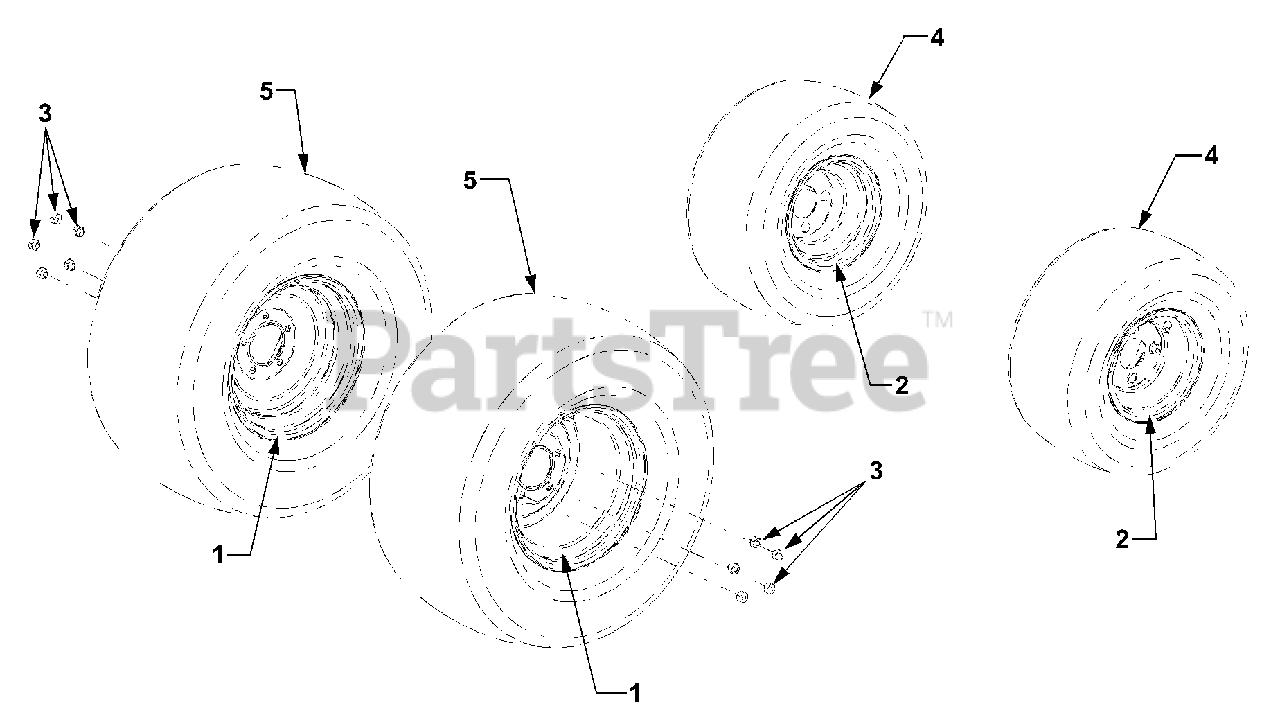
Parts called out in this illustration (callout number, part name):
1	Rim Assembly
2	Rim Assembly
3	Nut, Lug, 7/16-14
4	Tire, Turf, 18 x 8.5 x 8
5	Tire, Turf, 26 x 12.0 x 12
